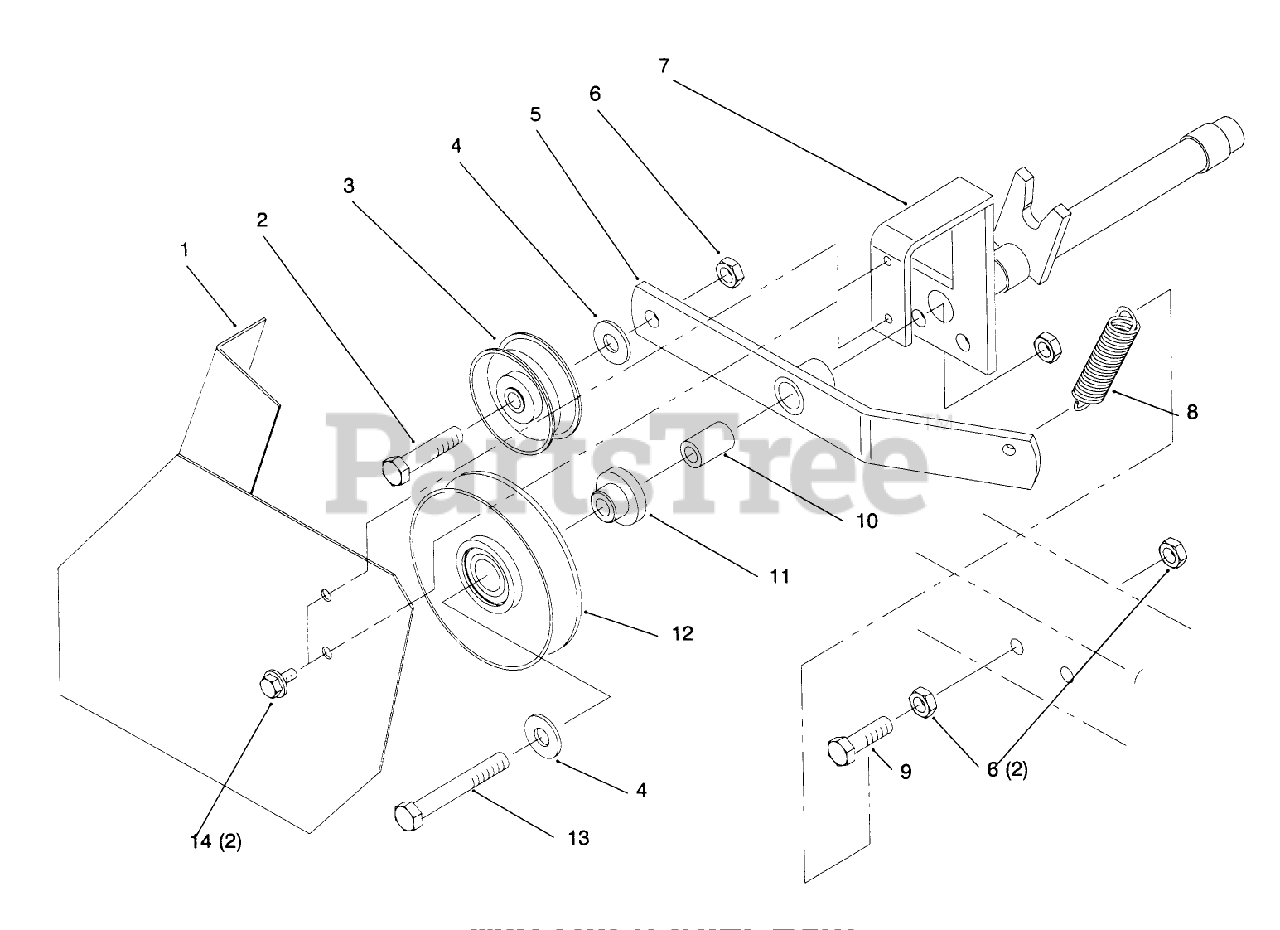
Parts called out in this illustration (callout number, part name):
1	ASM: FRONT IDLER R
2	SCREW-HH
3	IDLER PULLEY
4	WASHER-FLAT
5	ASSY IDLER ARM R
6	NUT-HEX
7	ASSY SUPPORT R
8	SPRING-BRAKE
9	SCREW-HH
10	SPACER
11	SPACER
12	PULLEY-IDLER
13	SCREW-HH
14	SCREW-HWH
